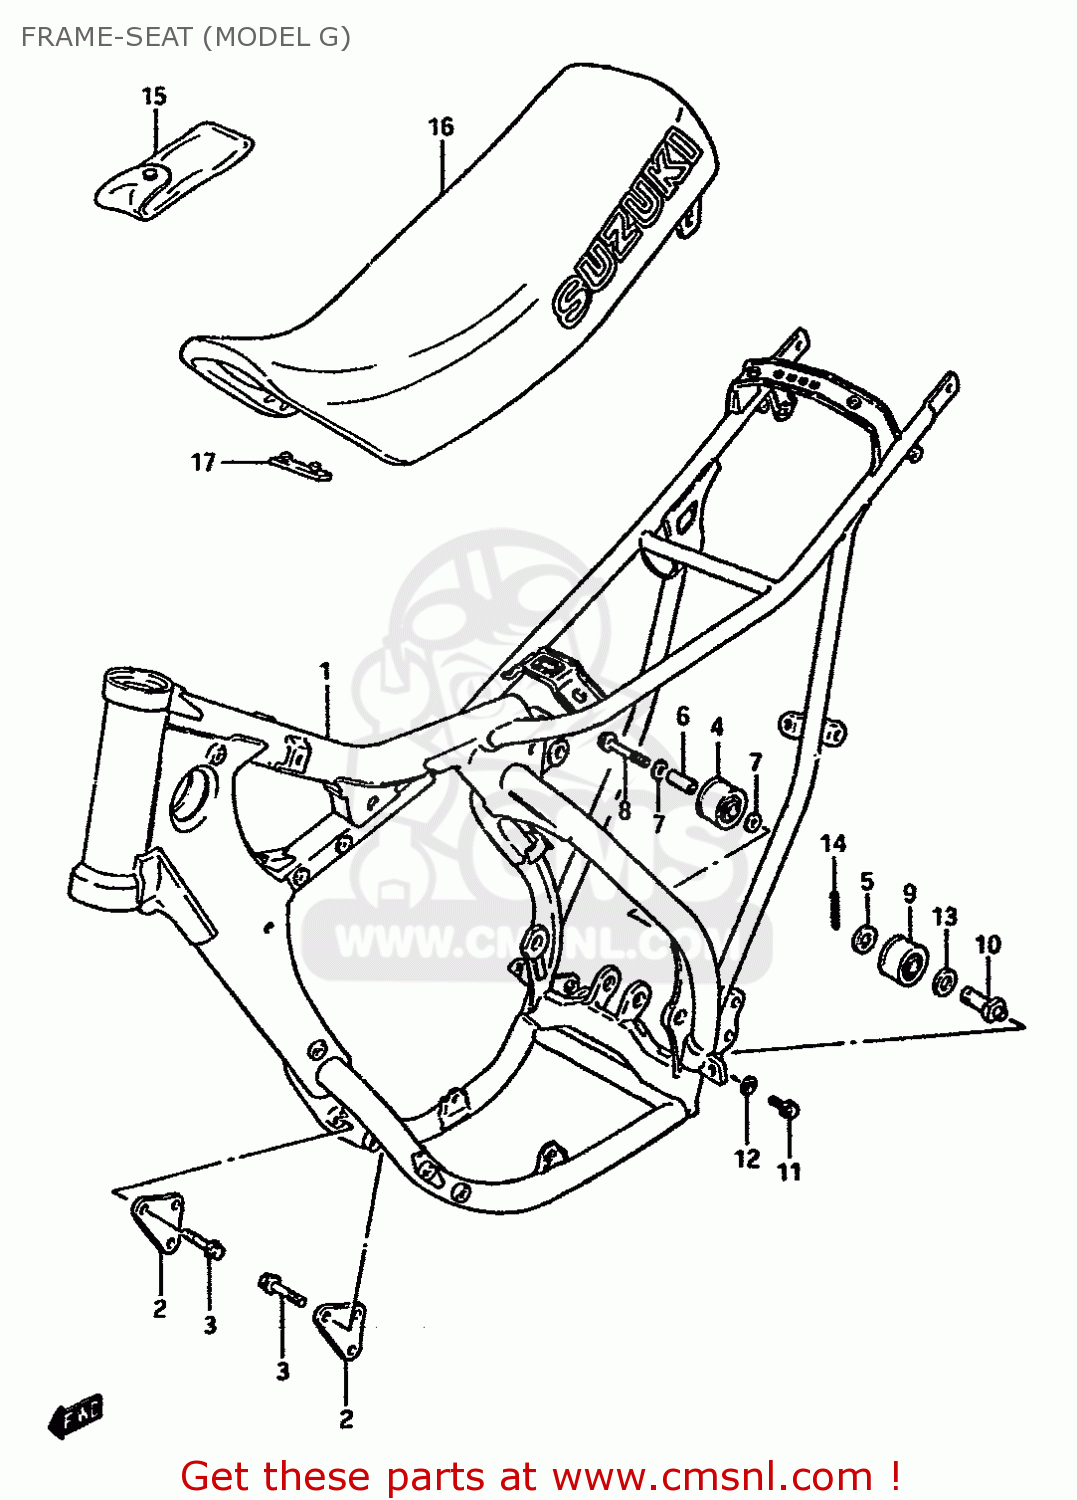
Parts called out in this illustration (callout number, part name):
1	FRAME
2	PLATE,ENGINE MOUNTING
3	BOLT(8X36)
4	ROLLER,CHAIN CONTROL
5	WASHER
6	SPACER(8.6X12X25.5)
7	WASHER
8	BOLT(8X45)
9	ROLLER,CHAIN CONTROL
10	BOSS,CHAIN LENGTH ROLLER
11	BOLT 6X16
12	WASHER
13	WASHER
14	PIN 25X20
15	TOOL SET
16	SEAT ASSY (BLUE)
17	CUSHION
